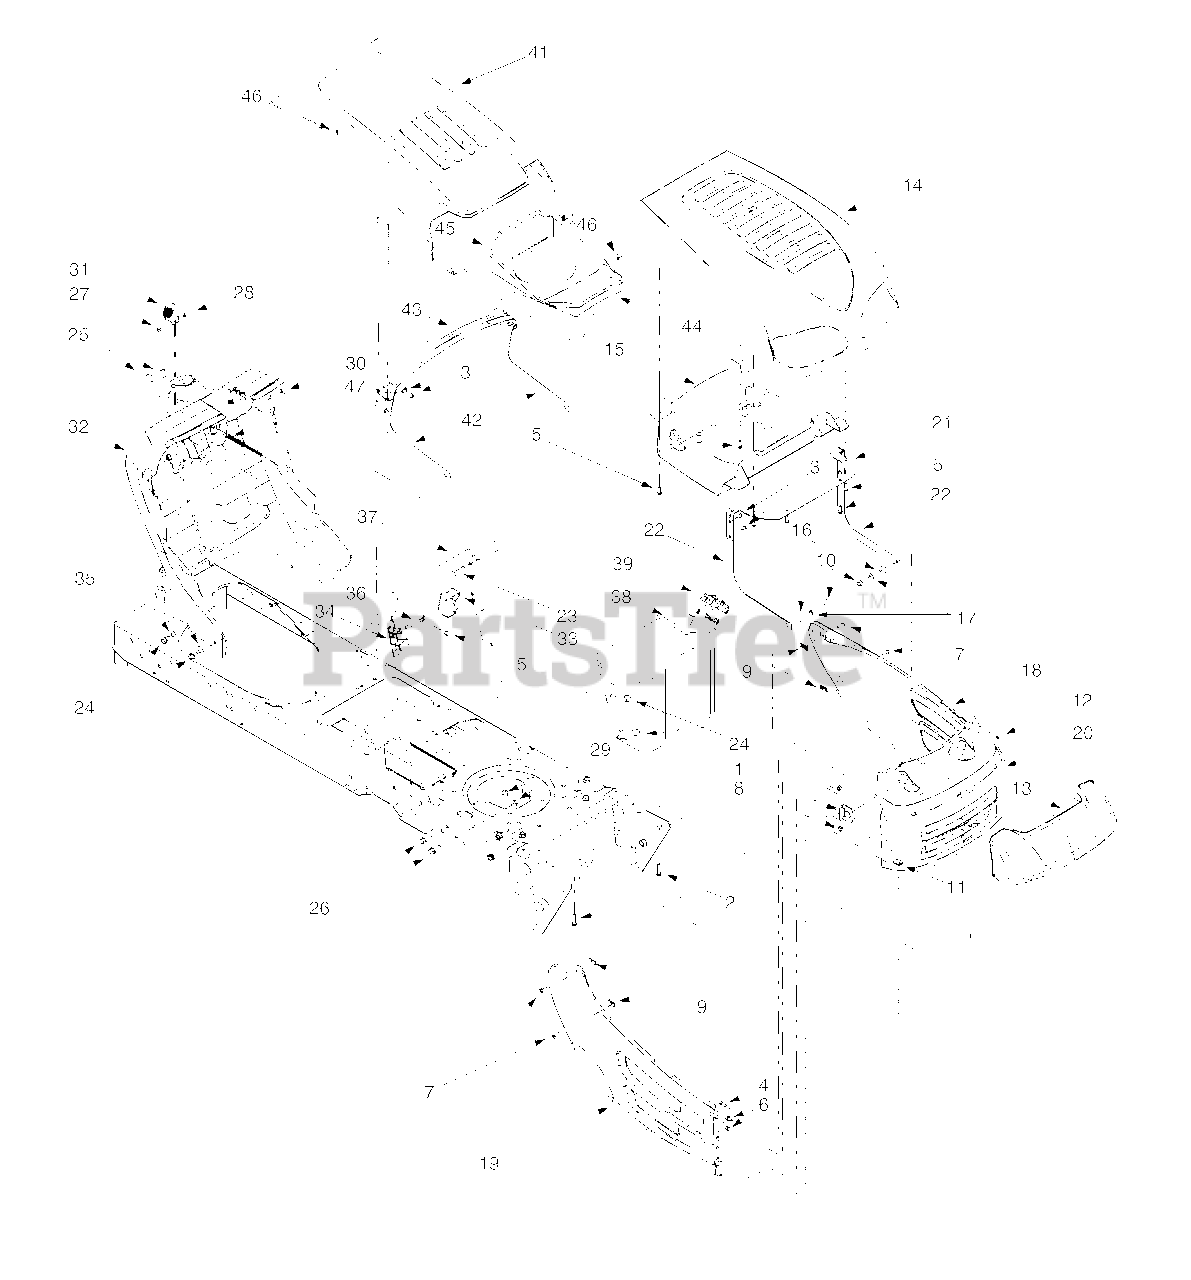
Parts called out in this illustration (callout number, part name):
2	Hex Cap Screw, 5/16-18 x 1.25
3	Self-tapping Screw, 1/4-20 x .5
4	Hex Cap Screw, 1/4-20 x .62
5	Self-tapping Screw, 1/4-15 x .75
6	Screw, 1/4-15 x .75
7	Phillips Pan Screw, 1/4-20 x .75
8	Hex Sems Nut, 1/4-20
9	U-type Speed Nut, 1/4-20
10	Flange Lock Nut, 3/8-16
11	U-nut, 5/16-18
12	Retainer Nut, 3/8
13	Headlight Lens
14	Hood, 7-style, Red
15	Hood Plenum, 7-style
16	Rubber Washer, .87 x .33
17	Bell Washer, .401 x .87 x .063
24	Self-Tapping Screw, 5/16-18 x .625
25	Truss Phillips Screw, 1/4-20 x .625
26	Hex Washer Screw, 5/16-18 x .625
27	Truss Phillips Screw, #8-32 x .375
28	Hex Nut, #8-32
29	Flange Lock Nut, 5/16-18
30	Hex Flange Lock Nut, 1/4-20
31	Throttle Control Knob
32	Dash Panel
33	Parking Brake Button
34	Plastic Plug
35	Flat Washer, .349 x 1.0 x .063
36	Pivot Rod
39	Fuel Cap (Fits Either Tank)
45	Heat Shield Support Rod
46	Ratchet Clip
47	Choke Cable/Knob
